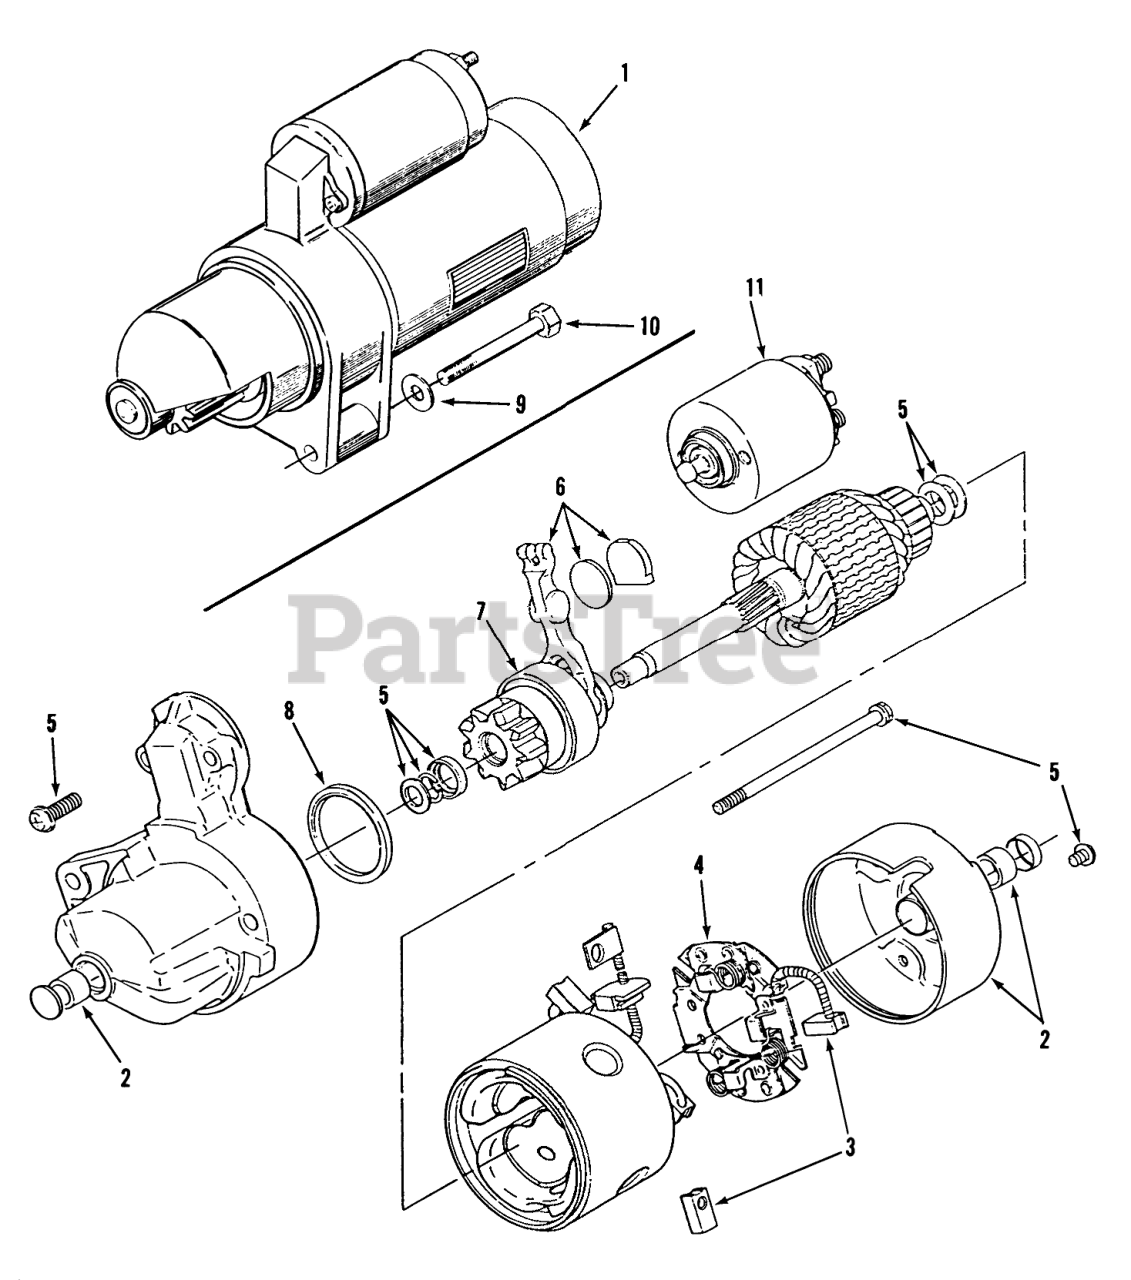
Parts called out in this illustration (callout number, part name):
1	Starter, Complete-See Components Below
2	Bushing Kit (Includes Frt Bushing and Rear Cap w/Bushing)
3	Starter Brush Kit (Includes Positive Brush (2) and Negative Brush w/Pigtail)
4	Starter Brush Holder (Includes Brush Holder w/ Negative Brush)
5	Starter Hdwr Kit (Includes Solenoid Screws (2), Brush Holder Screws (2), Thru Bolts (2), Armature Shims (2), Pinion Stop Collar, and Pinion Retaining Ring)
6	Starter Shift Lever Kit (Includes Shift Lever, Wear Plate and Rubber Plug)
7	StarterClutch (Includes Pinion Gearw/Clutch)
8	Dust Seal
9	Washer
10	Bolt
11	Starter Solenoid Kit (Includes Solenoid, Spring and Plunger)
